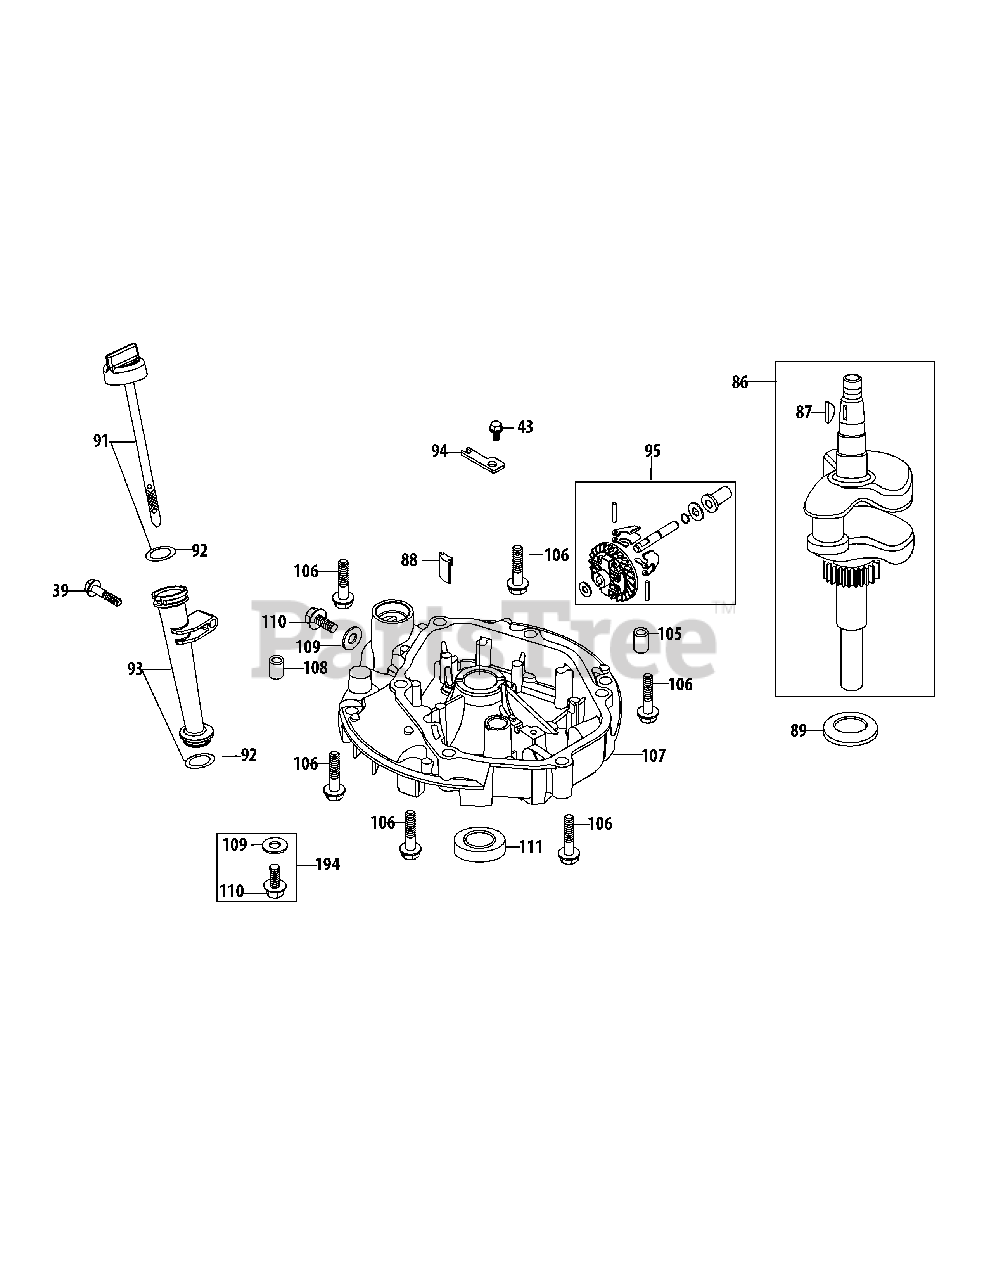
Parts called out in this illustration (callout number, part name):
39	Bolt M6X35
43	Bolt M6X14
86	Crankshaft Assembly
87	Flywheel Key
88	Oil Return Seal
89	Crankshaft Thrust Washer
92	Dipstick / Oil Fill Tube O-Ring
93	Oil Fill Tube
94	Governor Gear Mounting Plate
95	Governor Gear/Shaft Assembly
105	Crankcase Cover Dowel Pin 7×14
106	Bolt M6X28
107	Crankcase Cover
108	Crankcase Cover Dowel Pin 9×14
109	Oil Drain Plug Washer
110	Oil Drain Plug
111	Lower Crankshaft Seal
194	Oil Drain Plug And Washer Ass'y
